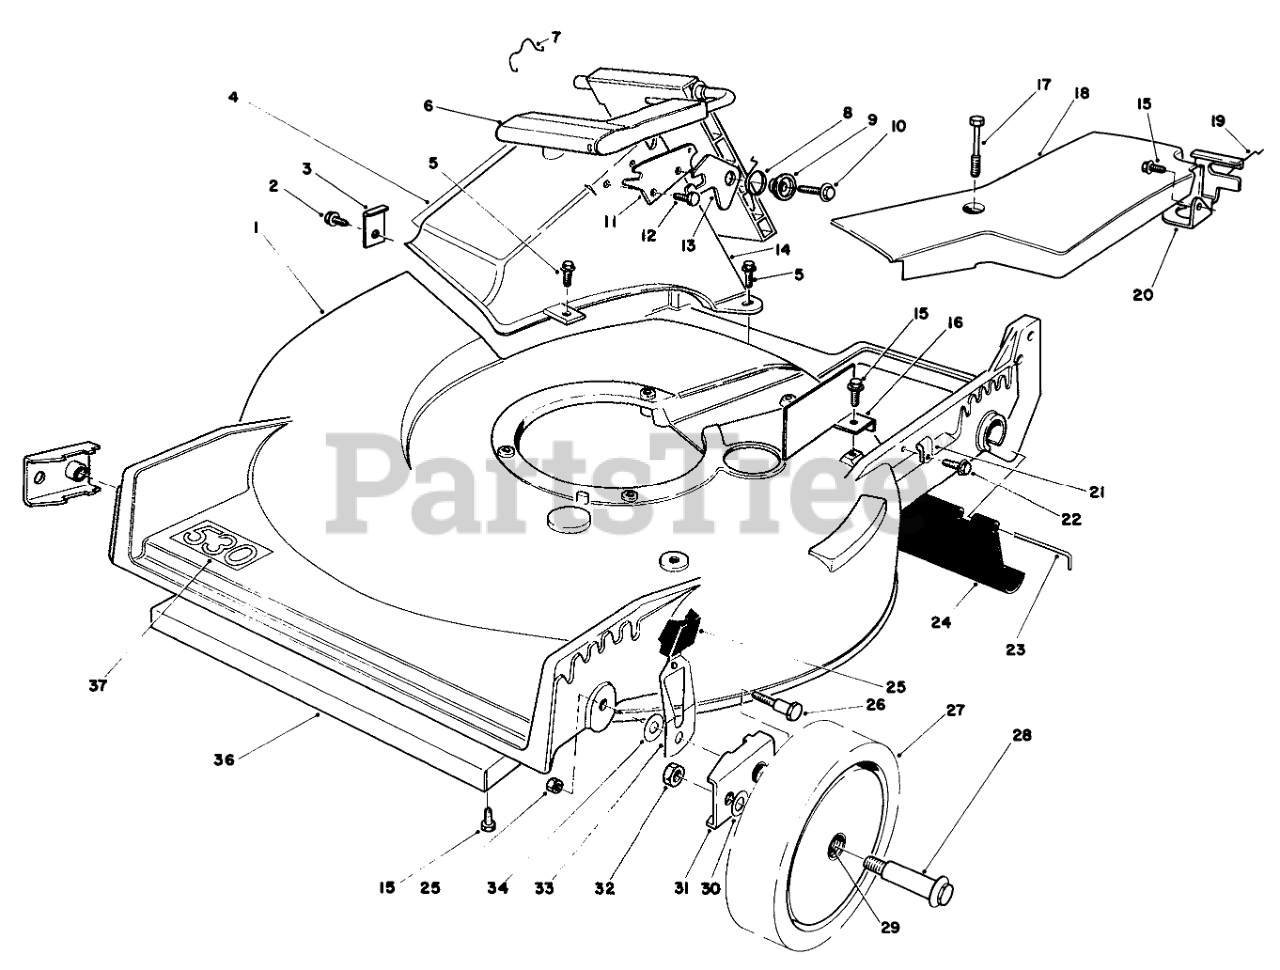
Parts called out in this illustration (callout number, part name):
1	21 SP RB HSG/DECAL
2	SCREW
3	TUNNEL CLIP
4	ATTENTION DECAL
5	SCREW-HWH
6	Discharge Door Assembly
7	DOOR RET SPRING
8	TORSION SPRING
9	DOOR SPACER
10	SCREW-HWH
11	DOOR LATCH PLATE
12	SCREW-PLASTITE
13	SAFETY LATCH
14	Tunnel Discharge
15	SCREW-HWHTF
16	Shield-Muffler
17	SCREW-HHFTF
18	Cover-Belt
19	RETAINER-CABLE
20	Bracket-Traction Adj.
21	CLAMP-CABLE
22	SCREW
23	ROD-SHIELD
24	SHIELD-TRAILING
25	KNOB-ARM
26	PIVOT SCREW
27	Wheel & Tire Assembly (Incl. Ref. #29)
28	WHEEL BOLT
29	BUSHING
30	WASHER
31	HP PIVOT ARM ASM
32	NUT-LOCK
33	Spring Arm
34	Washer
35	NUT-LOCK, NI
36	Shield-front
37	Decal-530
